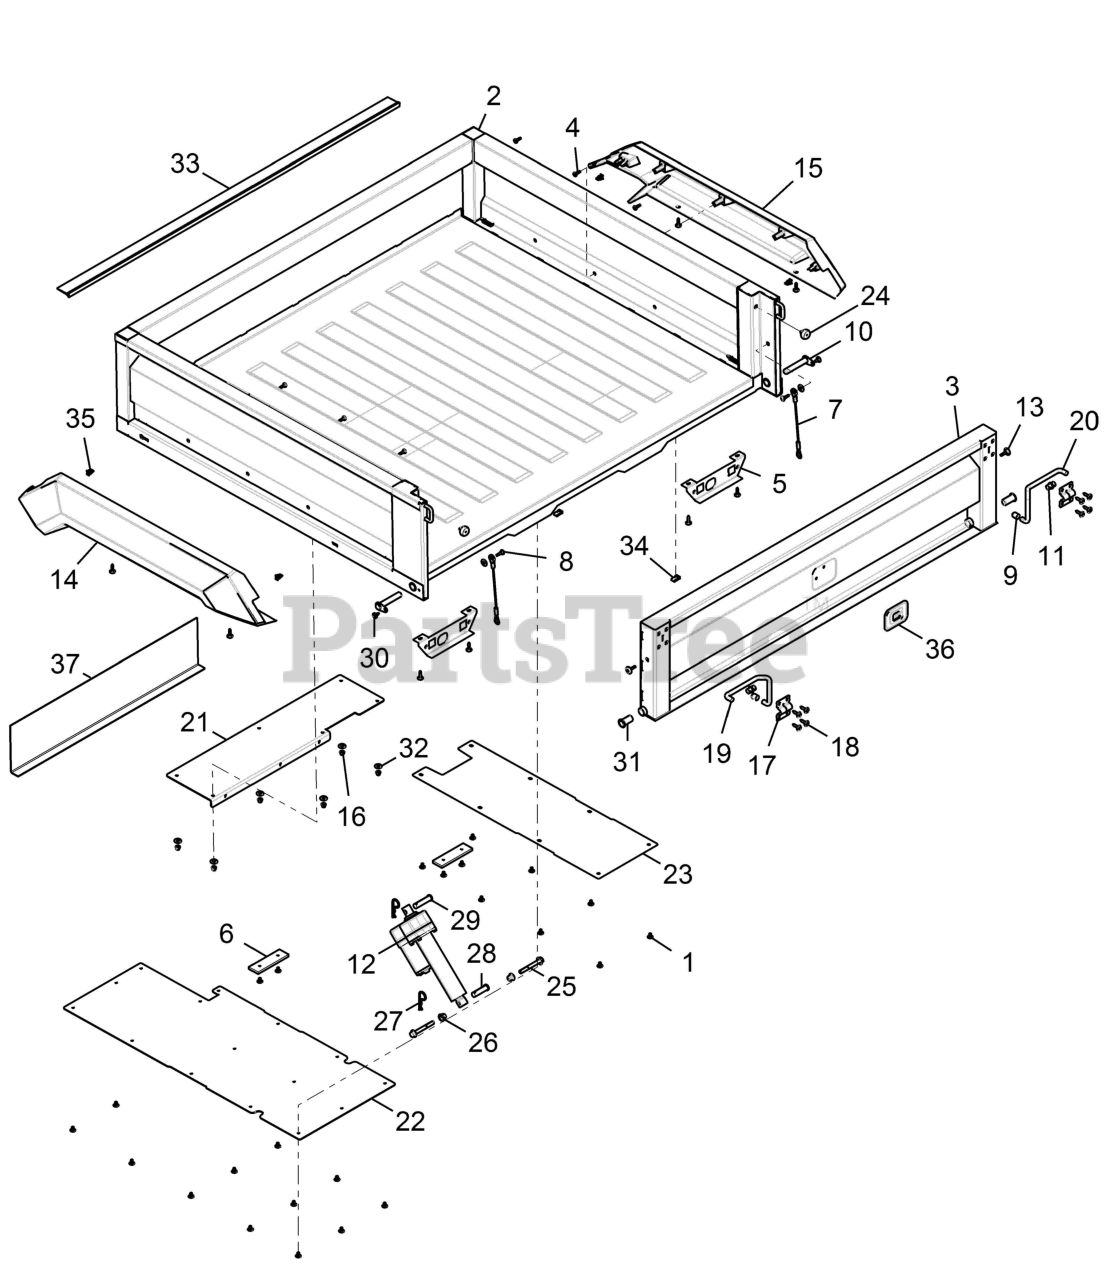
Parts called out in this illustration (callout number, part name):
1	RIVET(50) *
2	BOX, ARNS,GRAVELY RED
3	TAILGATE,ARNS,GRVLY RED
4	SCR-TXPH-#14 X .75 HI-LO RIE
5	BRKT.,TAILLIGHT MOUNT,RED
6	BUMPER-BOX BASE
7	TAILGATE CABLE
8	BLT-SHLDR .188X.188X.25-20
9	CAP, TAILGATE LATCH
10	PIN-TAILGATE MOUNT
11	BUSHING, TAILGATE LATCH
12	ACTUATOR-BOX LIFT,SPLY
13	SCR-TXTH-M6X1.0X25 RIE,SHDR
14	FLARE-BOX,LH,ARIENS
15	FLARE-BOX,RH,ARIENS
16	NUT-M6 FLANGE,NYLOK
17	BRKT-TAILGATE LATCH
18	SCR-TXTH-M6X1.0X25 RIE
19	ROD, LATCH, LH
20	ROD, LATCH, RH
21	SHIELD, HEAT, EXHAUST, FRONT
21	SHIELD, FRONT EXHAUST HEAT
22	SHIELD, HEAT, EXHAUST, REAR
22	SHIELD, REAR EXHAUST HEAT
23	SHIELD, HEAT EXHAUST MID
24	BUMPER, TAILGATE
25	SCR-HXFL-M10X1.25X80 8.8 ZOD
26	NUT-M10X1.25,FLG,NYLOC-OLIVE D
27	CLIP, HITCH PIN
28	PIN, CLEVIS
29	PIN, CLEVIS BOX LIFT 2"
30	SCR-M6X1X16 TR/TX-M
31	BUSHING, TAILGATE PIVOT PIN
33	TRIM,BOX
34	CLIP-U SPEED NUT
35	CLIP, DASH TRIM METAL
37	SHIELD, BED HEAT FOIL
